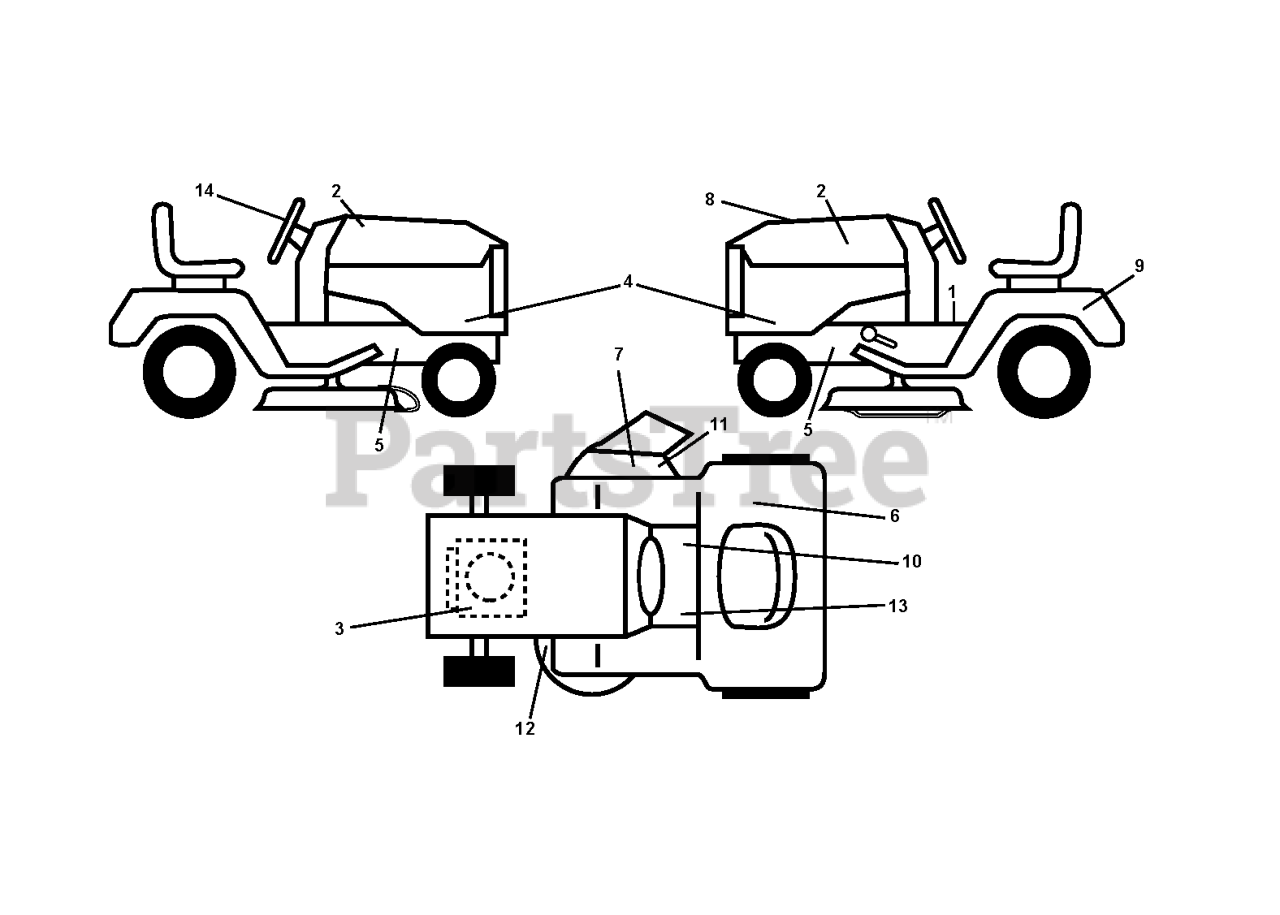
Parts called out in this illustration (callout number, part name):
1	LABEL
2	DECAL.HOOD.NAMELOGO.HUSQ
3	DECAL
6	Decal, Fender 100 DB/CE
7	DECAL.INTERNATIONL.CUTFINGER
9	DECAL BTRY SYMBOLS
10	DECAL PARK BRAKE
11	DECAL, DEFLECT WARNING
12	DECAL.V-BELT.SCHEMATIC.36/38/9
13	DECAL
14	DECAL.WHEEL.STRG.LGN.H
